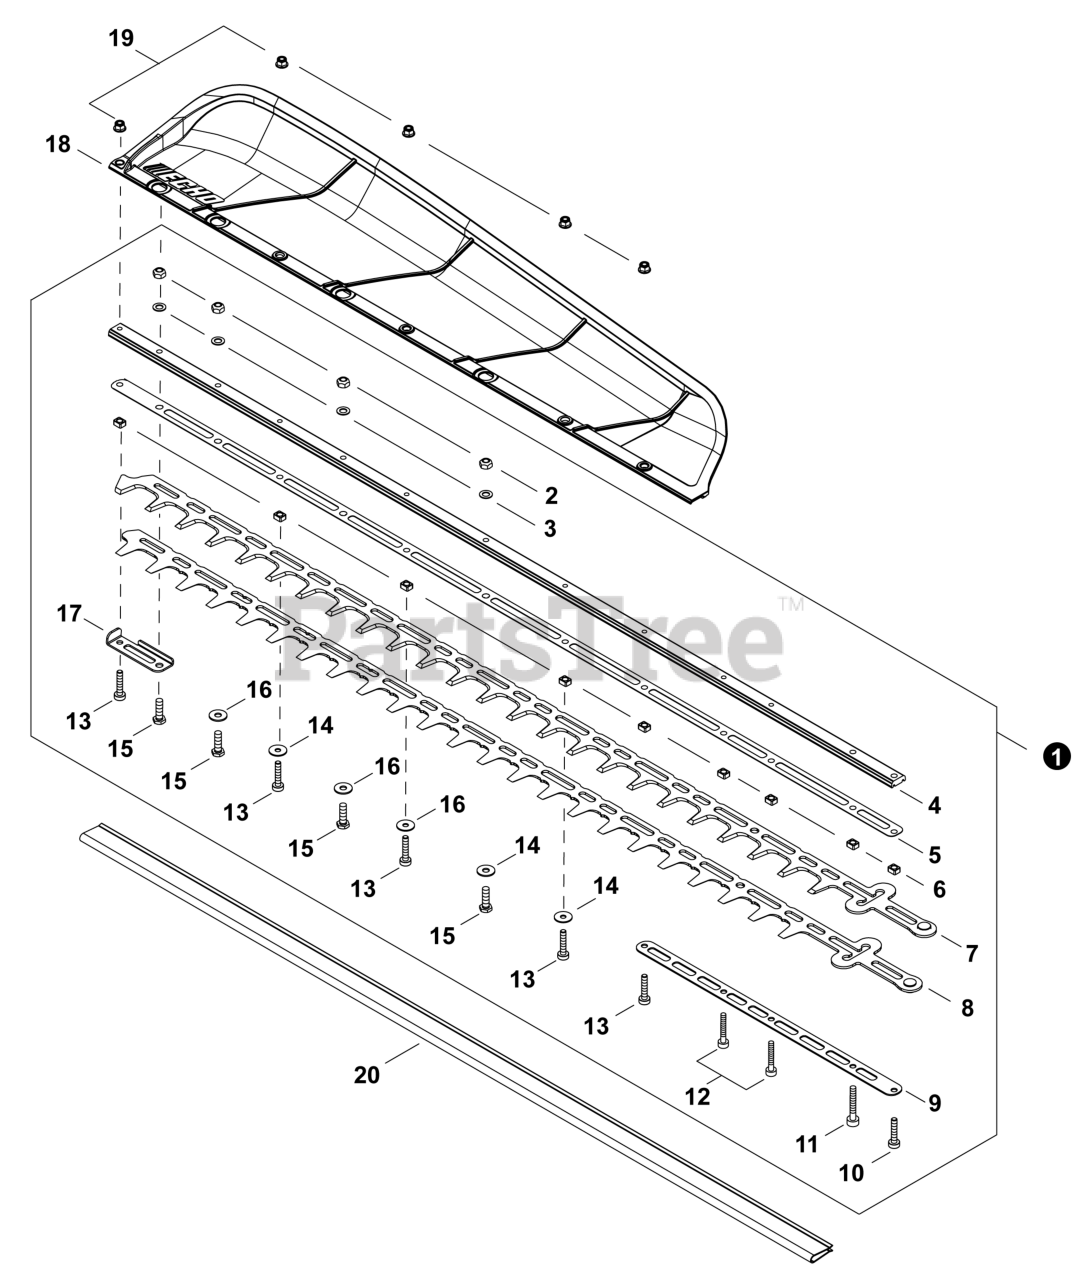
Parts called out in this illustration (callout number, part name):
1	CUTTER ASSY, 40"
3	WASHER 6.5x11.5x0.8
4	SUPPORT, CUTTER 40"
5	PLATE, CUTTER 40"
6	GUIDE, BLADE
7	CUTTER 40" - UPPER
8	CUTTER 40" - LOWER
9	PLATE, CUTTER
10	BOLT, TORX 5x25
11	BOLT, TORX 5x35
12	BOLT, TORX 5x30
13	BOLT, TORX 5x25
15	BOLT M6x20
16	WASHER M6
17	SUPPORT, CUTTER
18	DEFLECTOR, DEBRIS 40"
19	NUT, FLANGE M5
20	SCABBARD 40"
